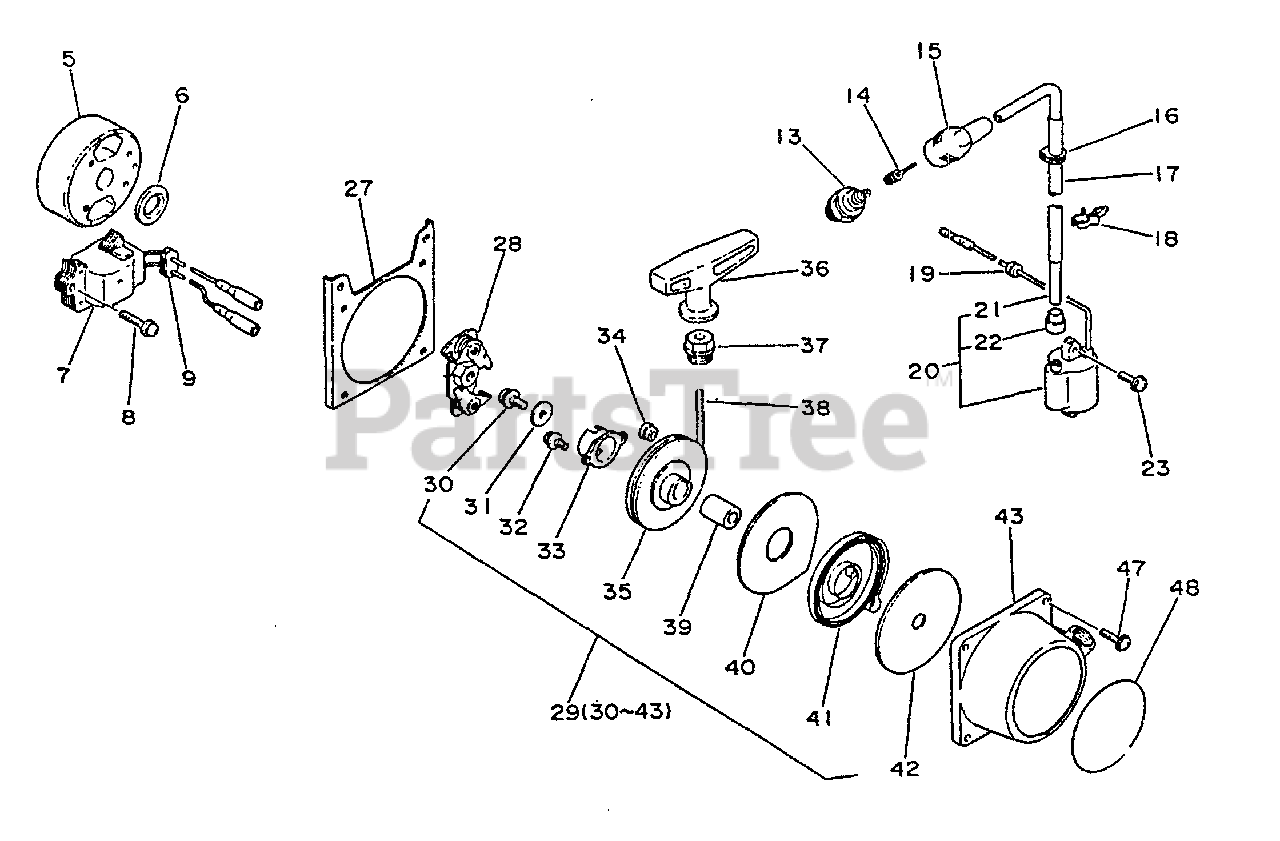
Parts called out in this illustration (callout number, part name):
5	FLYWHEEL
7	COIL, IGNITION
8	SCREW - 4X20
13	SPARK PLUG -- BPM-7A
14	TERMINAL, SPARK PLUG CAP
15	CAP, SPARK PLUG
20	IGNITION COIL ASSY
21	CORD, HIGH TENSION
22	CORD, HIGH TENSION
23	SCREW - 4X14
28	STARTER PAWL ASSY
29	STARTER ASSY
30	SCREW - 5X10
31	WASHER - 5
32	SCREW - 4X8
33	CATCHER, PAWL
34	RETAINER, ROPE
35	REEL, ROPE
36	GRIP, STARTER
37	GUIDE, ROPE
38	ROPE, STARTER - 3.5X850
40	PLATE, STARTER
41	SPRING, REWIND
42	PLATE, STARTER
43	CASE, STARTER
47	SCREW - 4X16
48	LABEL - ECHO
